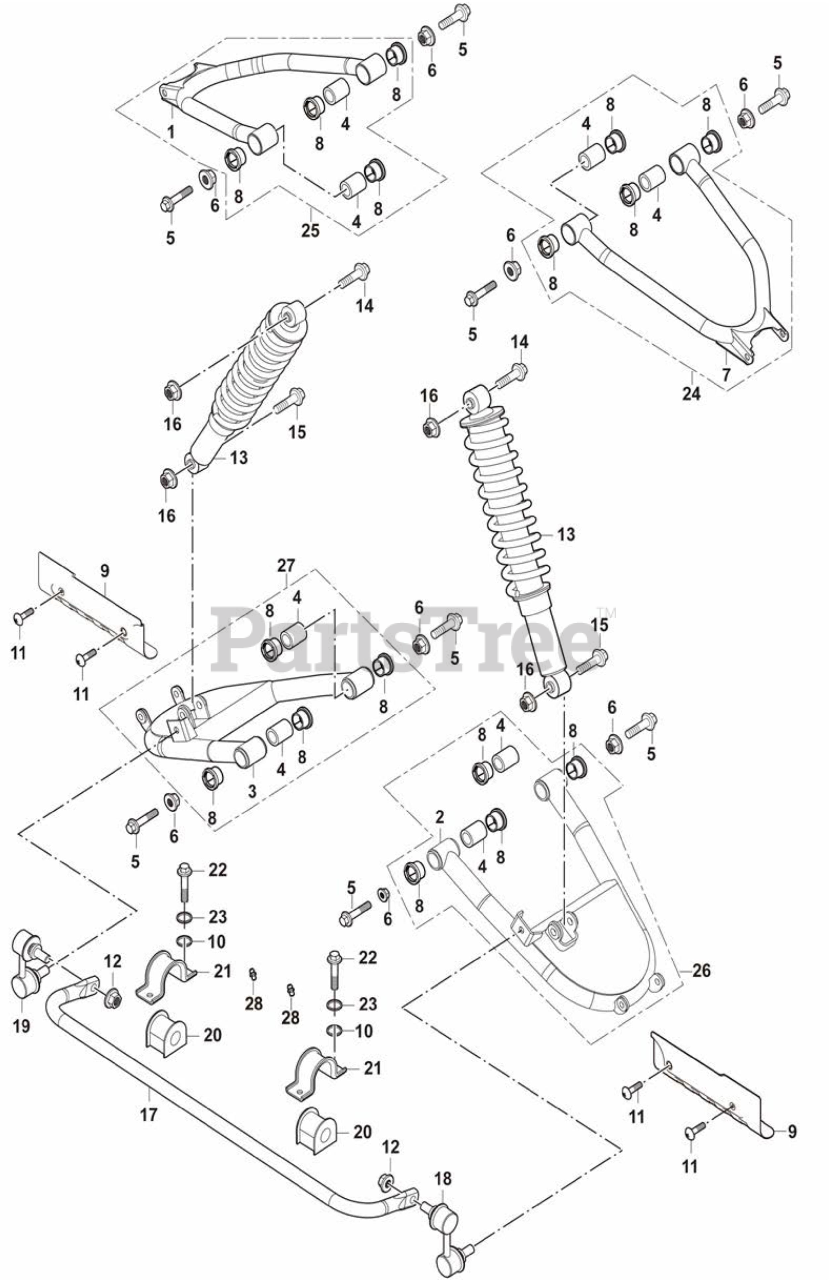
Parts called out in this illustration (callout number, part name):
1	Rear-Upper Suspension (R)
2	Rear-Lower Suspension (L)
3	Rear-Lower Suspension (R)
4	Bush 10.3X23X50
5	Hexagon Flange BoltM10X1.25X70
6	Hexagon Flange Self-Lock Nuts M10x1.25
7	Rear-Upper Suspension (L)
8	Bush 22X28
9	Rear Protection Plate, Suspension ( R)
11	Cross Large Plate Head Screw M6X16
12	Hexagon Locking Nut M10X1.25
13	Rear Shock Absorber D
14	Hexagon Flange BoltM10X1.25X70
15	Hexagon Nut M10X1.25X65
16	Hexagon Flange Self-Lock Nuts M10x1.25
17	Rear balancing lever
18	Ball joint,left balancing lever
19	Ball joint,right balancing lever
20	Cushion Bush 20X45,balancing lever
21	mounting cap,cushion rubber
22	Hexagon Flange Bolt M8X30
23	Spring Washer-8
24	Rear left upper rocker arm
25	Rear right upper rocker arm
26	Rear left lower rocker arm
27	Rear right lower rocker arm
28	Swing arm nozzle
